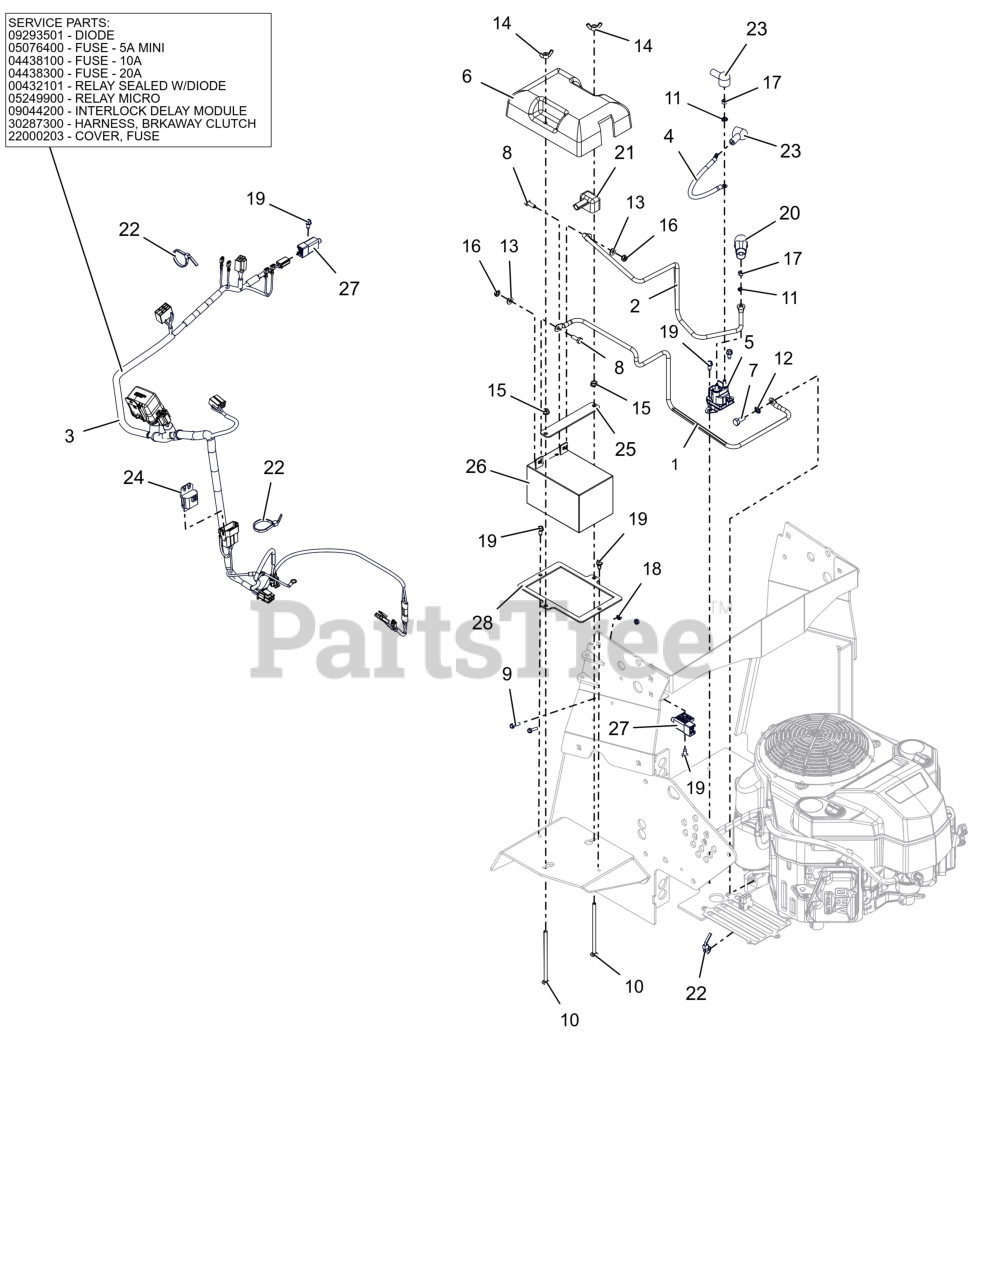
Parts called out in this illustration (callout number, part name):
1	CABLE, NEGATIVE BATTERY
2	CABLE, RED- .31X30.00 (6) X .25
3	HARNESS- WIRING
3	DIODE, CONNECTOR SHELL
3	FUSE, 5 AMP MINI-ATC
3	FUSE,10 AMP MINI-ATC
3	FUSE,20 AMP MINI ATC
3	RELAY,SEALED W/DIODE
3	RELAY,SPNO,SEALED,ISO280,RESIS
3	MODULE,INTERLOCK,DELAY, 1801
3	HARNESS, BREAKAWAY CLUTCH
3	COVER, FUSE
4	CABLE-POSITIVE BATTERY 9.00"
5	SOLENOID, STARTER (SEALED)
6	COVER, BATTERY
7	BLT, HEX M8-1.25X20 G8.8 ZCC
8	BLT, HEX .25-20X.75 G5 ZCC
9	BLT, HWH #10-24X.75 ZCC
10	BLT- RHSN .25-20X5.0 ZCC
11	WSHR,LK-EXT.262X.502X.026 ZCC
12	WSHR,LK-EXT .326X.599X.031 ZCC
13	WSHR,FLT .281X.625X.065 ZCC
14	NUT- LK-WING .25-20 ZCC
15	NUT-LK-CTR-FLG .25-20 ZC120
16	NUT-KEPS .250-20 ZCC
17	NUT-STD M6-1.0 ZCC
18	NUT, KEPS #10-24 ZCC
19	SCR-TAP .25-20X.50 HWH ZCC
20	BOOT, .65ID POS
21	INSULATOR
22	CABLE TIE LG 5-1/2
23	BOOT, EYELET TERMINAL
24	MODULE,INTERLOCK,DELAY, 1801
25	BAR, BATTERY STRAP (BLACK)
26	BATTERY, 12V 12AH -190CCA
27	SWITCH-BRAKE NO/NO-POST & HOLE
28	HOLDER- BATTERY
